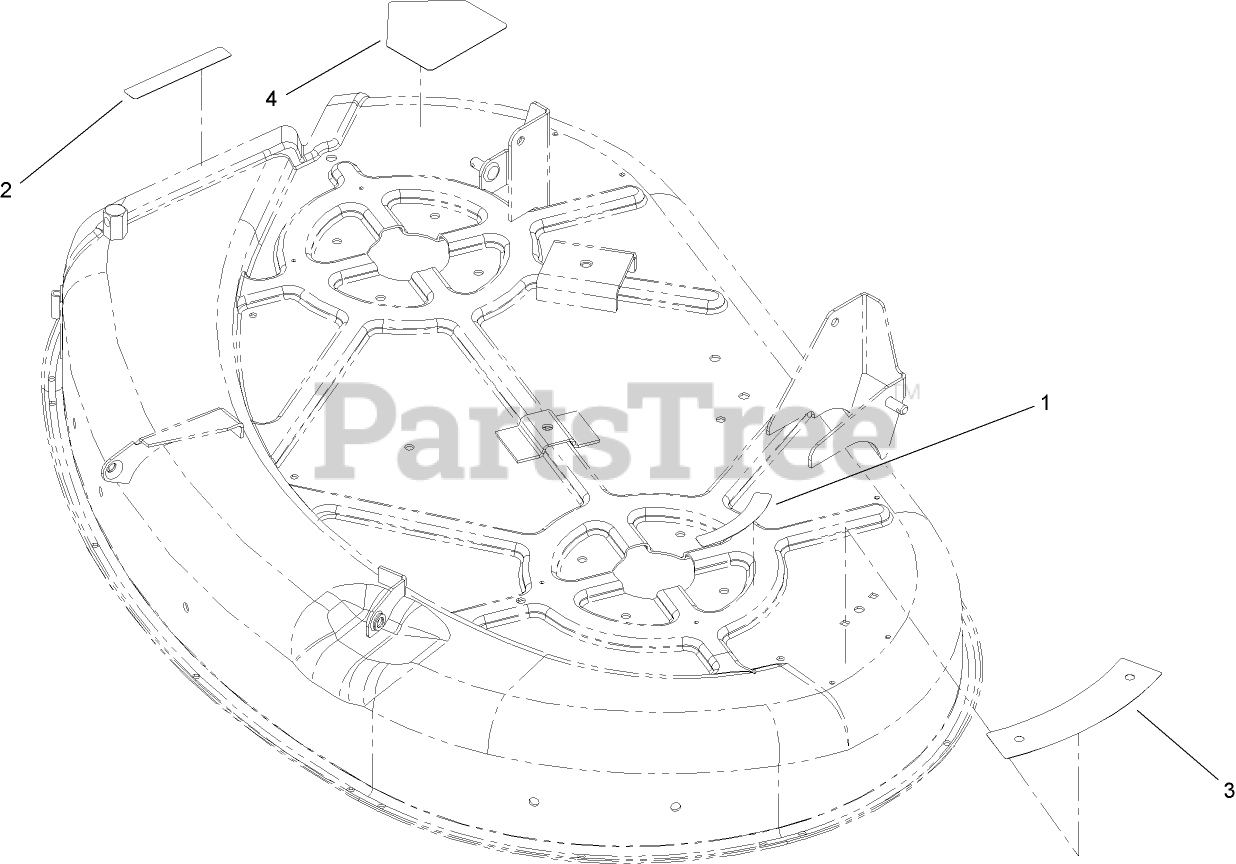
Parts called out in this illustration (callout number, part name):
1	DECAL-DANGER, SHIELD
2	DECAL-DANGER
3	DECAL-DANGER
4	DECAL-DANGER
